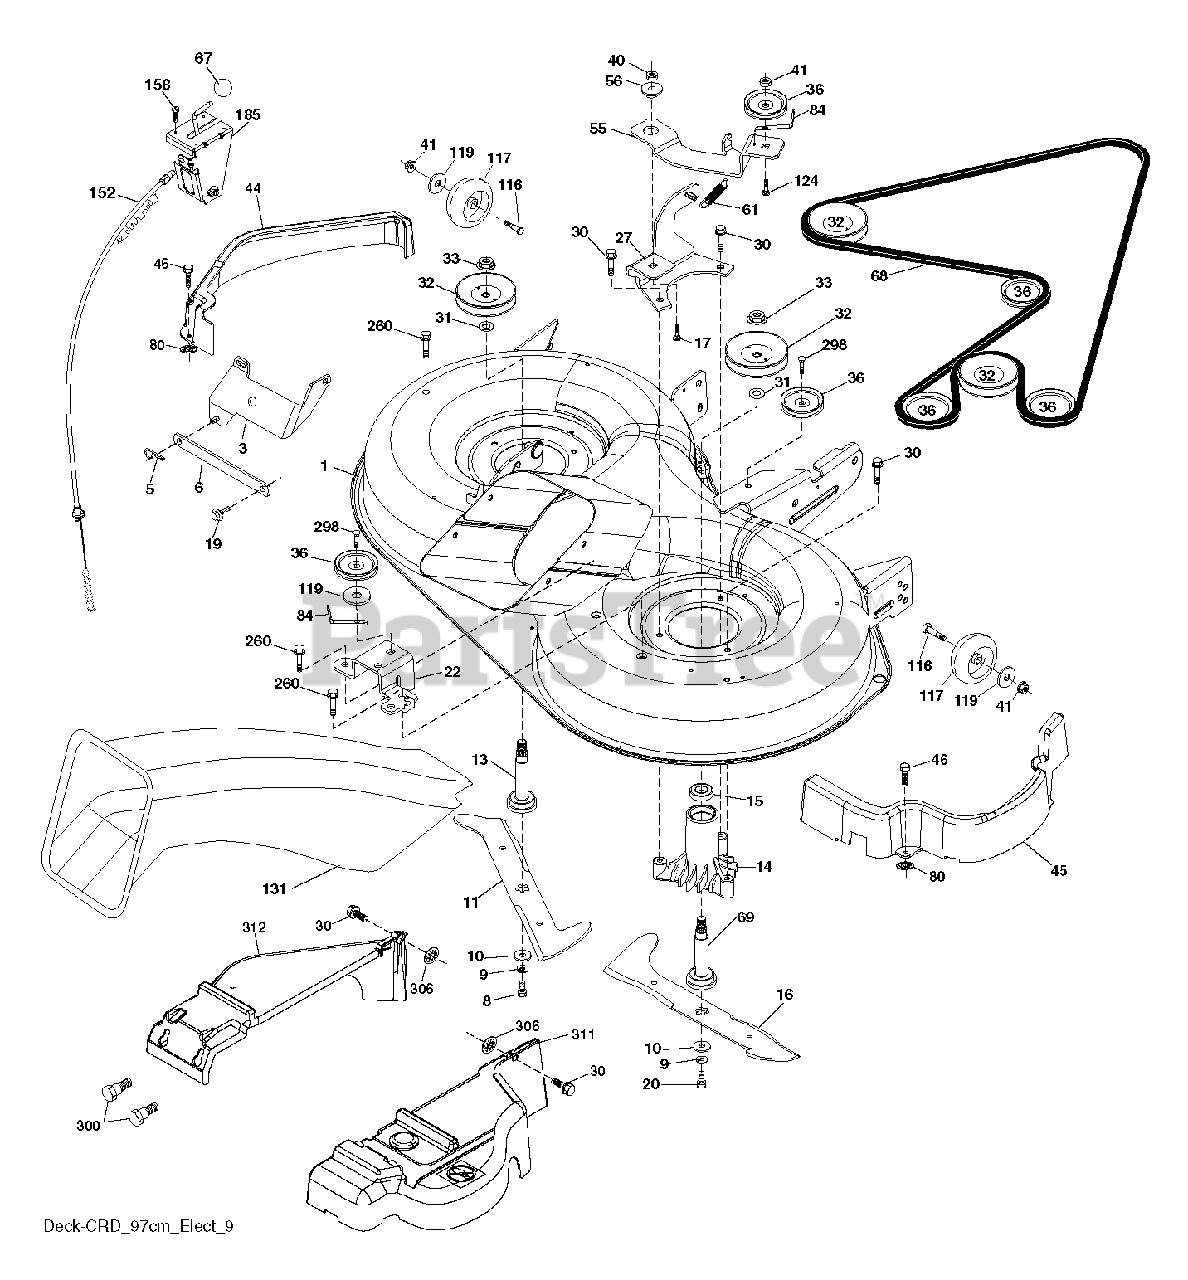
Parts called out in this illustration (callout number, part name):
1	DECK.WLDT.97.CRD.2GWB.
3	BRACKET.ASM.BAR.SWAY.CHASS
5	Retainer Spring
6	BAR.SWAY.92.CRD
8	BOLT.3/8-24X1.25 GR8
9	LOCKWASHER
10	WASHER.BLADE
11	BLADE.3N1.LH.CRD.97
13	SHAFT ASM VENT
14	HOUSING.MANDREL.VENTED (MACHD)
16	BLADE.3N1.RH.CRD.97
17	BOLT.3/8-14X1.25
19	BOLT SHD 5/16-18
20	BOLT.3/8-24X1.25GR8. LHTHRD
22	BRACKET.SUPT.IDLER.REAR.RH
27	BRACKET.ASM.SUSP.REAR.RH.
30	SCREW, WASHER HEAD
31	WASHER.SPACER.MANDREL
32	PULLEY MANDREL
33	NUT.FLANGE.LOCK.TOP
36	PULLEY.IDLER.4.25
41	NUT LOCK FLG 3/8-16 UNC
44	COVER MANDREL LEFT
45	COVER MANDREL RIGHT
46	SCREW.1/4-20X5/8
55	ARM.IDLER.92 CRD.2006
56	SPACER.RETAINER.MOWER
61	SPRING
67	KNOB T (3/8 HOLE)
68	BELT.DRIVE.CRD.97.2010
69	SHAFT.ASM.W/LWR.BRG.RH.THREAD
80	PALNUT 1/4
84	KEEPER, BELT IDLER
116	BOLT.SHOULDER.3/8-16X3-5/8.
117	WHEEL. GUAGE RALLY
119	WASHER
124	BOLT.3/8-16X1.50
131	CHUTE BAGGER
158	SCREW
185	HEAD ASM. CABLE CLUTCH
260	SCREW 3/8-16X1/2
298	SCREW LT
300	BOLT.SHOULDER
306	WASHER 5/16"
311	COVER RIGHT
312	COVER LEFT
